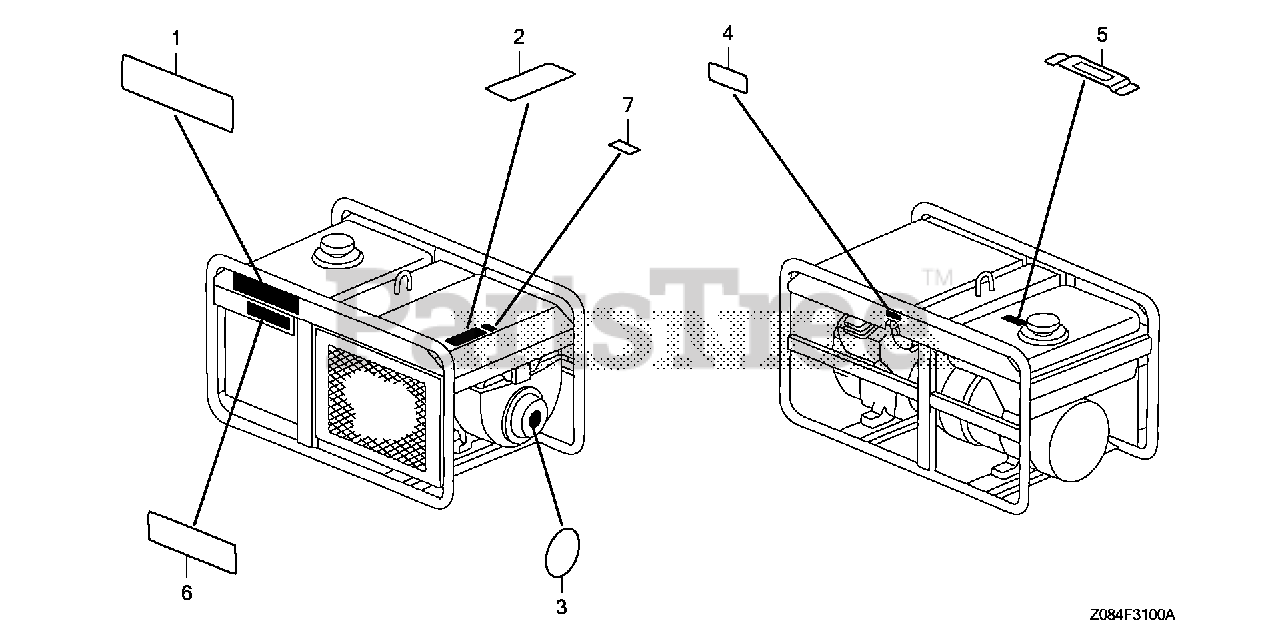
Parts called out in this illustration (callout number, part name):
1	EMBLEM (EB11000)
2	LABEL, OPERATOR WARNING
3	MARK, OIL ALERT
3	MARK, HONDA
4	MARK, EX. CAUTION
5	PLATE, FUEL INDICATION
6	MARK, WARNING (GFCI)
